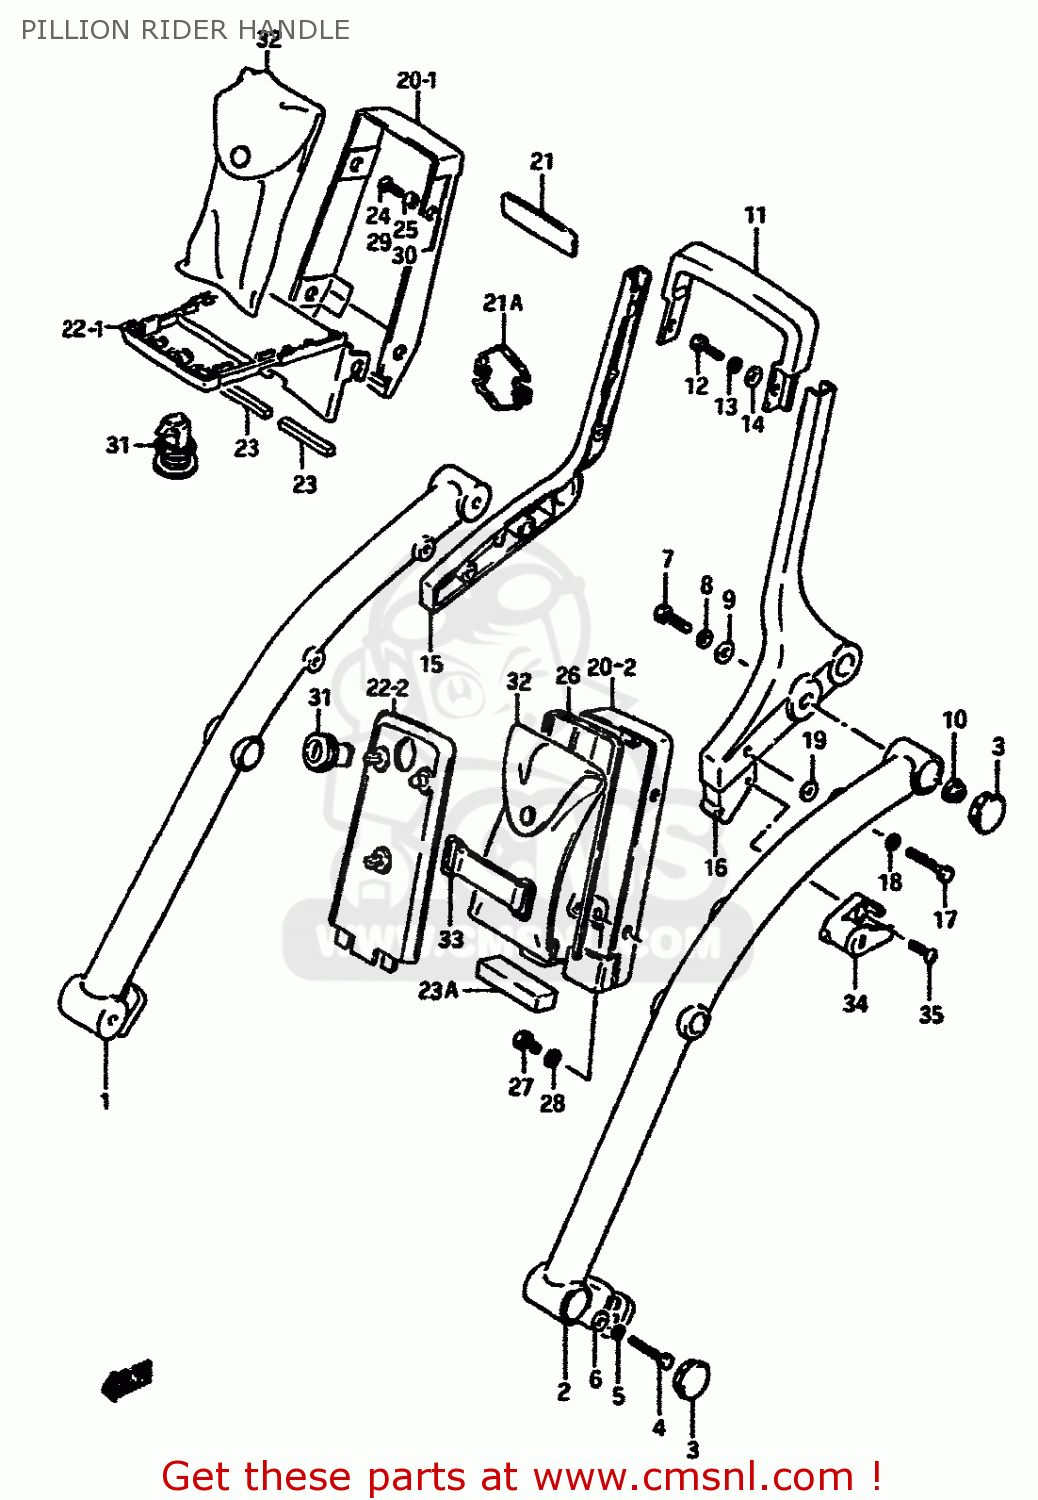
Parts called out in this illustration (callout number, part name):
1	GRIP,FRAME HANDLE
2	GRIP,FRAME HANDLE,LEFT
3	CAP,FRAME HANDLE GRIP
4	BOLT,FRONT
5	WASHER,LOCK,8.
6	WASHER
7	BOLT
8	LOCK WASHER
9	WASHER
10	NUT, WHEEL SET
11	HANDLE,PILLION RIDER
12	BOLT
13	WASHER,LOCK
14	WASHER
15	HANDLE,PILLION RIDER
16	HANDLE,PILLION RIDER
17	BOLT ,6X35
18	WASHER,LOCK
19	WASHER, LOWER
20	HOLDER,TOOL RR
21	EMBLEM
21A	EMBLEM
22	HOLDER,TOOL FR
23	CUSHION,TOOL HOLDER
23A	CUSHION,TOOL BACK
24	SCREW
25	SPACER
26	MOLDING,TOOL HOLDER RR
27	BOLT
28	WASHER,LOCK
29	SCREW
30	SPACER (5.5X8X4)
31	LOCK SET,TOOL HOLDER
32	TOOL ASSY
33	BAND
34	LOCK SET,HELMET
35	SCREW
